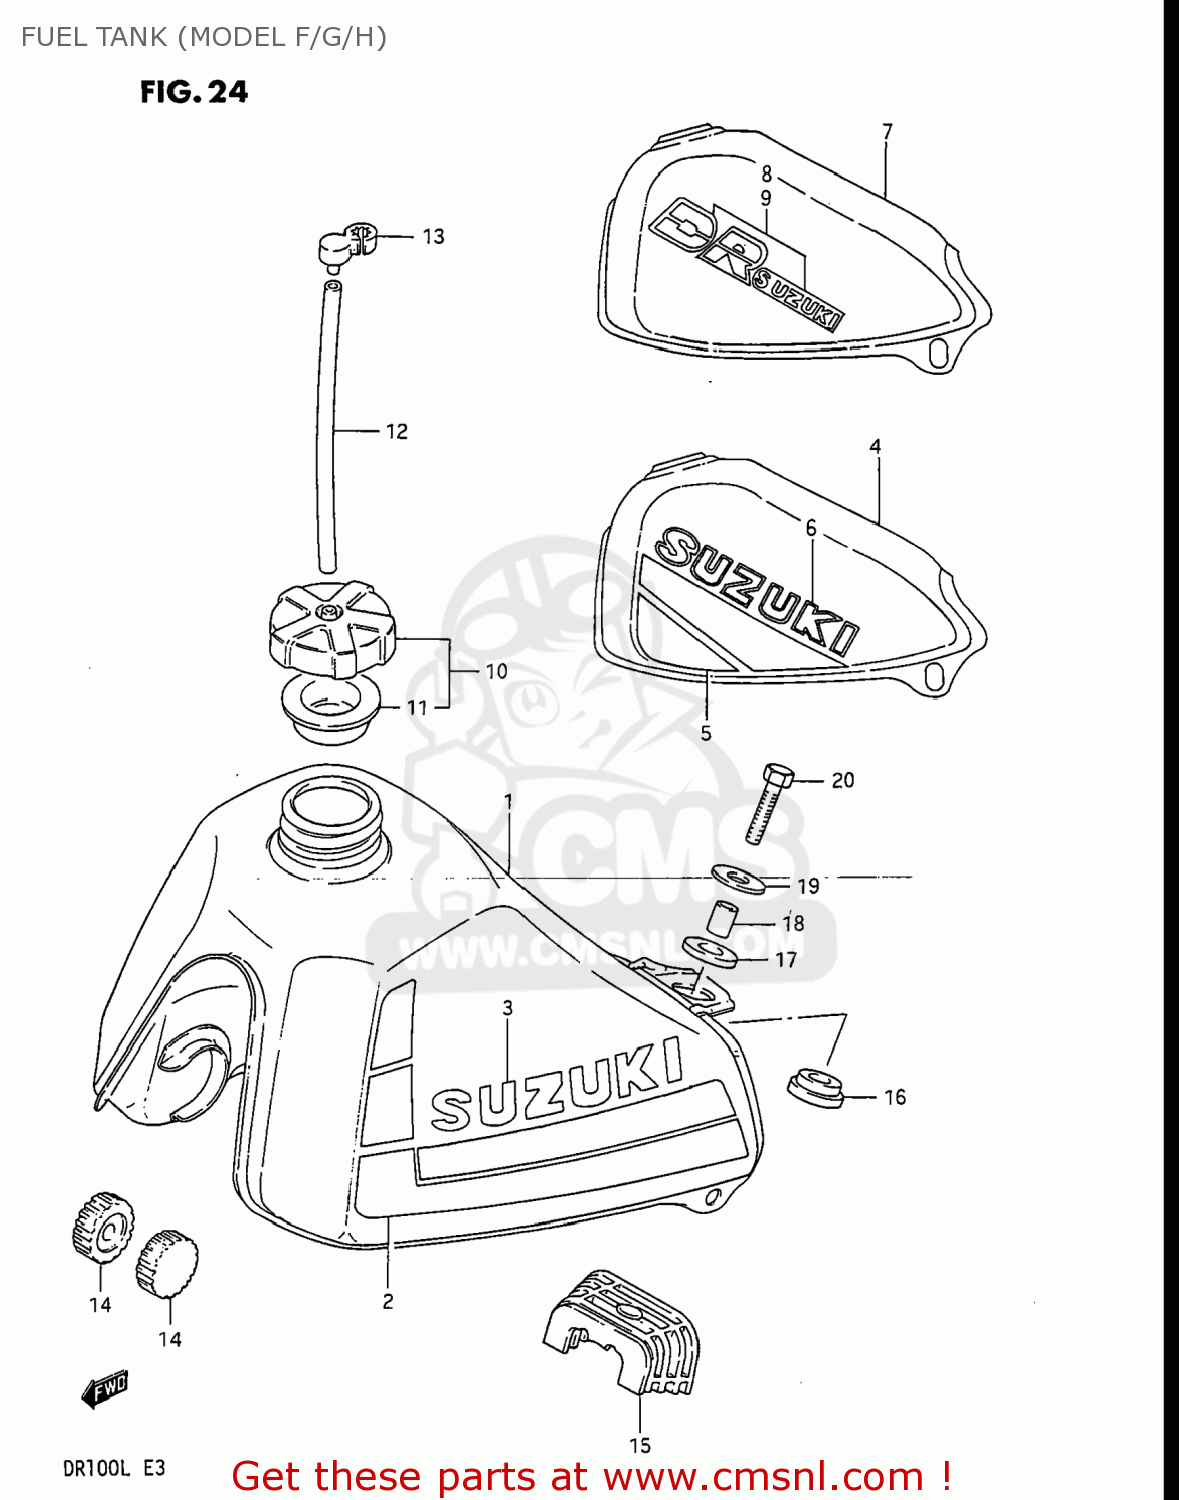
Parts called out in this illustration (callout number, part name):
1	TANK ASSEMBLY,FUEL
2	TAPE SET,FUEL TANK
3	EMBLEM
4	TANK ASSEMBLY,FUEL
5	TAPE SET,FUEL TANK
6	EMBLEM
7	TANK ASSEMBLY,FUEL
8	EMBLEM
9	EMBLEM,FUEL TANK
10	CAP SET,FUEL TANK
11	GASKET (NAS)
12	HOSE
13	CLAMP,FUEL TANK BREATHER HOSE
14	CUSHION
15	CUSHION,FUEL TANK
16	CUSHION
17	CUSHION
18	SPACER(8.5X12X19)
19	WASHER (8.5X29X1.6)
20	BOLT
